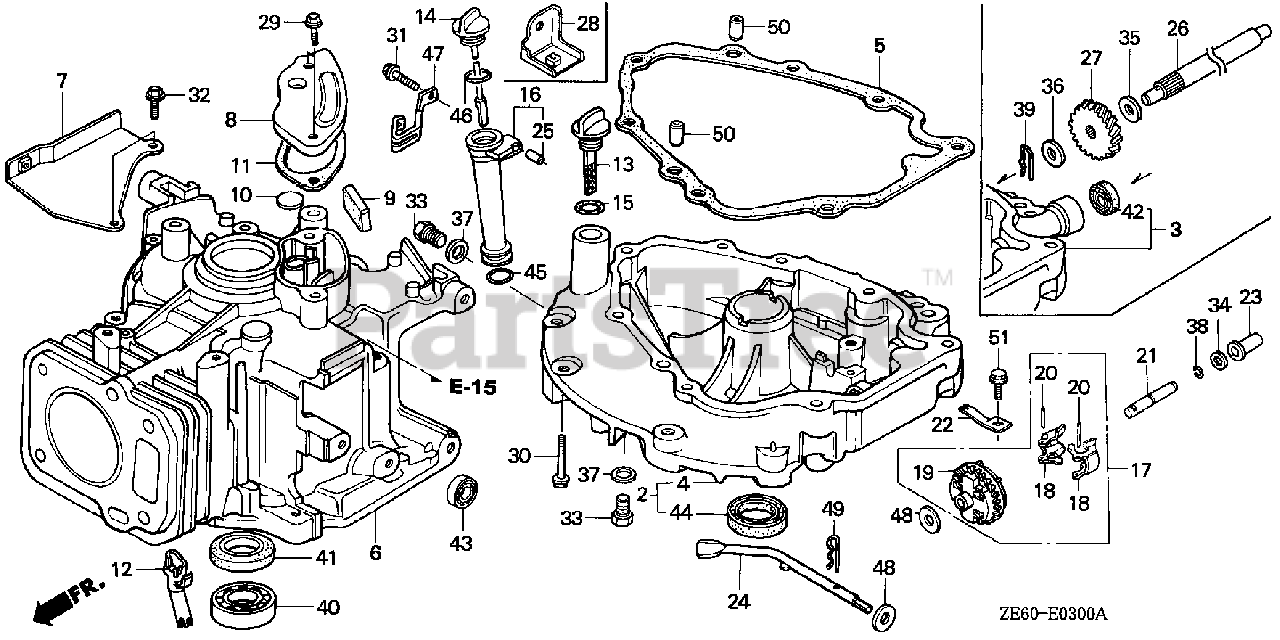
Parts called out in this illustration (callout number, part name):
2	PAN ASSY., OIL (USA)
5	GASKET, OIL PAN
6	CYLINDER
7	PLATE, GUIDE
8	CAP, BREATHER CHAMBER
9	FILTER, BREATHER
10	VALVE, BREATHER
11	GASKET, BREATHER CHAMBER
12	PIPE, OIL DEFENSE
14	GAUGE, OIL LEVEL
16	EXTENSION, OIL FILLER (NOT AVAILABLE)
17	GOVERNOR ASSY.
18	WEIGHT, GOVERNOR
19	HOLDER, GOVERNOR WEIGHT
20	PIN, GOVERNOR WEIGHT
21	SHAFT, GOVERNOR HOLDER
22	PLATE, GOVERNOR SHAFT HOLDER
23	SLIDER, GOVERNOR
24	SHAFT, GOVERNOR ARM
25	COLLAR, EXTENSION
29	BOLT, FLANGE (6X14) (CT200)
30	BOLT, FLANGE (6X28)
31	BOLT, FLANGE (6X32)
32	BOLT, FLANGE (6X20)
33	BOLT, DRAIN PLUG
34	WASHER, THRUST (6MM)
37	WASHER, DRAIN PLUG (10.2MM)
38	CLIP, GOVERNOR HOLDER
40	BEARING, RADIAL BALL (62/22)
41	OIL SEAL (22X35X6)
43	OIL SEAL (6X11X4) (ARAI)
44	OIL SEAL (25X38X7)
44	OIL SEAL (25X38X7) (ARAI)
45	O-RING (26X2.7)
46	O-RING (22.1X2.2)
48	WASHER, PLAIN (6MM)
49	PIN, LOCK (8MM)
50	PIN, DOWEL (8X14)
51	BOLT, FLANGE (6X12)
